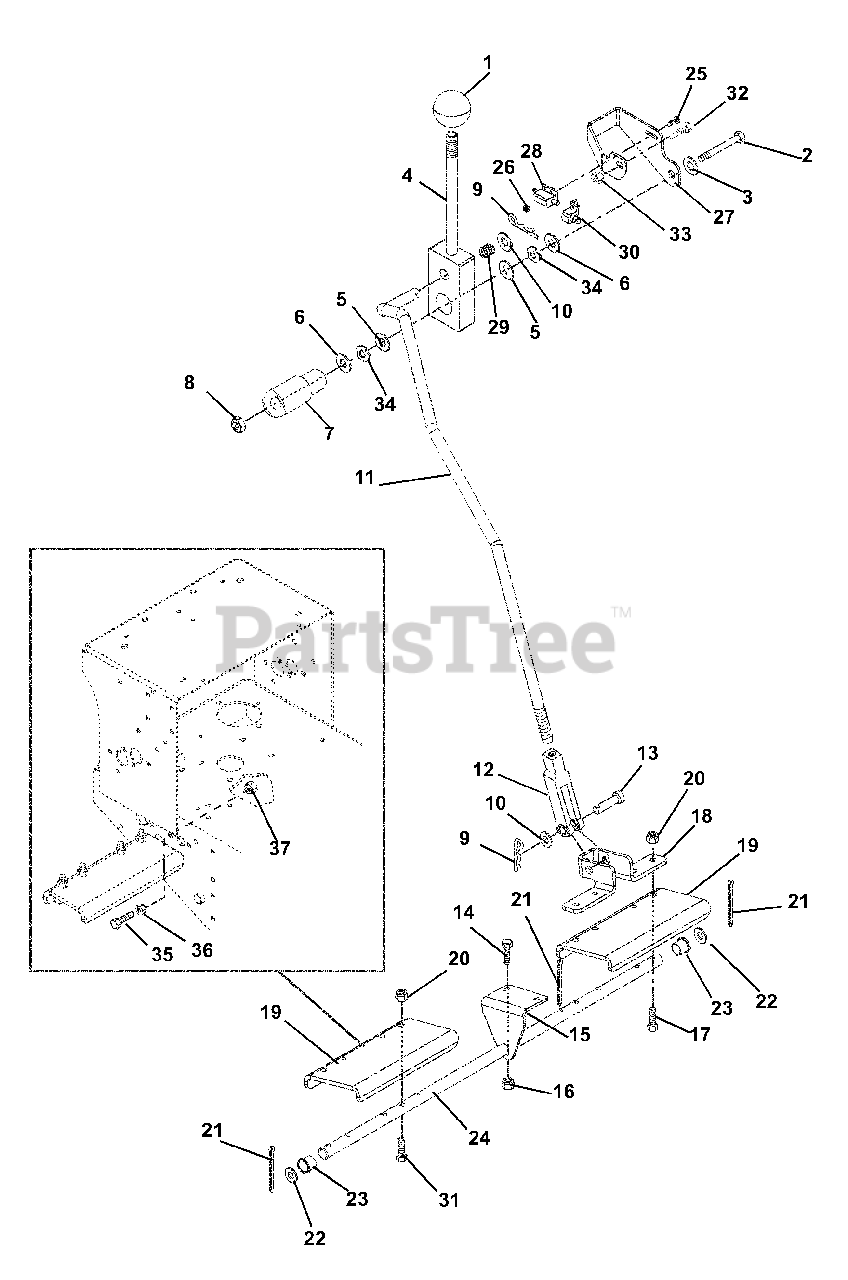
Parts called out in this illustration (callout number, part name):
1	Knob, Black Ball 1.47" .375-16
2	Bolt, Hex .44-14 x 4.5 Grade 5
3	Washer, Flat Steel .50 x 1.25 x .083
4	Weldment, Handle
5	Washer, Flat Nylon .76 x 1.25 x .030
6	Washer, Flat Steel .76 x 1.38 x .062
7	Pivot, Brake
8	Nut, Locking Hex .44-14
9	Pin, Hair Internal .08 x .18 x 1.18
10	Washer, Flat Steel .406 x .812 x .065
11	Rod, Brake
12	Clevis, .38-24 Adjustable
13	Pin, Clevis .37 x 1.75
14	Bolt, Hex .38-16 x 1.00 Grade 5
15	Bracket, Brake Shaft
16	Nut, Locking Nylon .38-16
17	Bolt, Hex .25-20 x 1.50 Grade 5
18	Brake, Arm
19	Pad, Brake
20	Nut, Locking Nylon .25-20
21	Pin, Cotter .12 x 1.00
22	Washer, Flat Steel .656 x 1.31 x .095
23	Bushing, Flange .63 x 1.00 x .625 Nylon
24	Brake, Shaft
25	Screw, Machine 10-24 x .75 Hex Washer Head
26	Nut, Locking Nylon 10-24 with Insert
27	Bracket, Brake Switch
28	Switch, Interlock
29	Spring, Compression .045 x .60 x .75
30	Boot, Rubber
31	Bolt, Hex .25-20 x 1.25 Grade 5
32	Bolt, Hex .31-18 x .75 Grade 5
33	Nut, Locking Top Flange .31-18
34	Washer, Wave .076 x 1.12 x .080
35	Bolt, Hex .38-16 x 1.75 Grade 5
36	Nut, Hex .38-16
37	Nut, Locking Nylon .38-16
